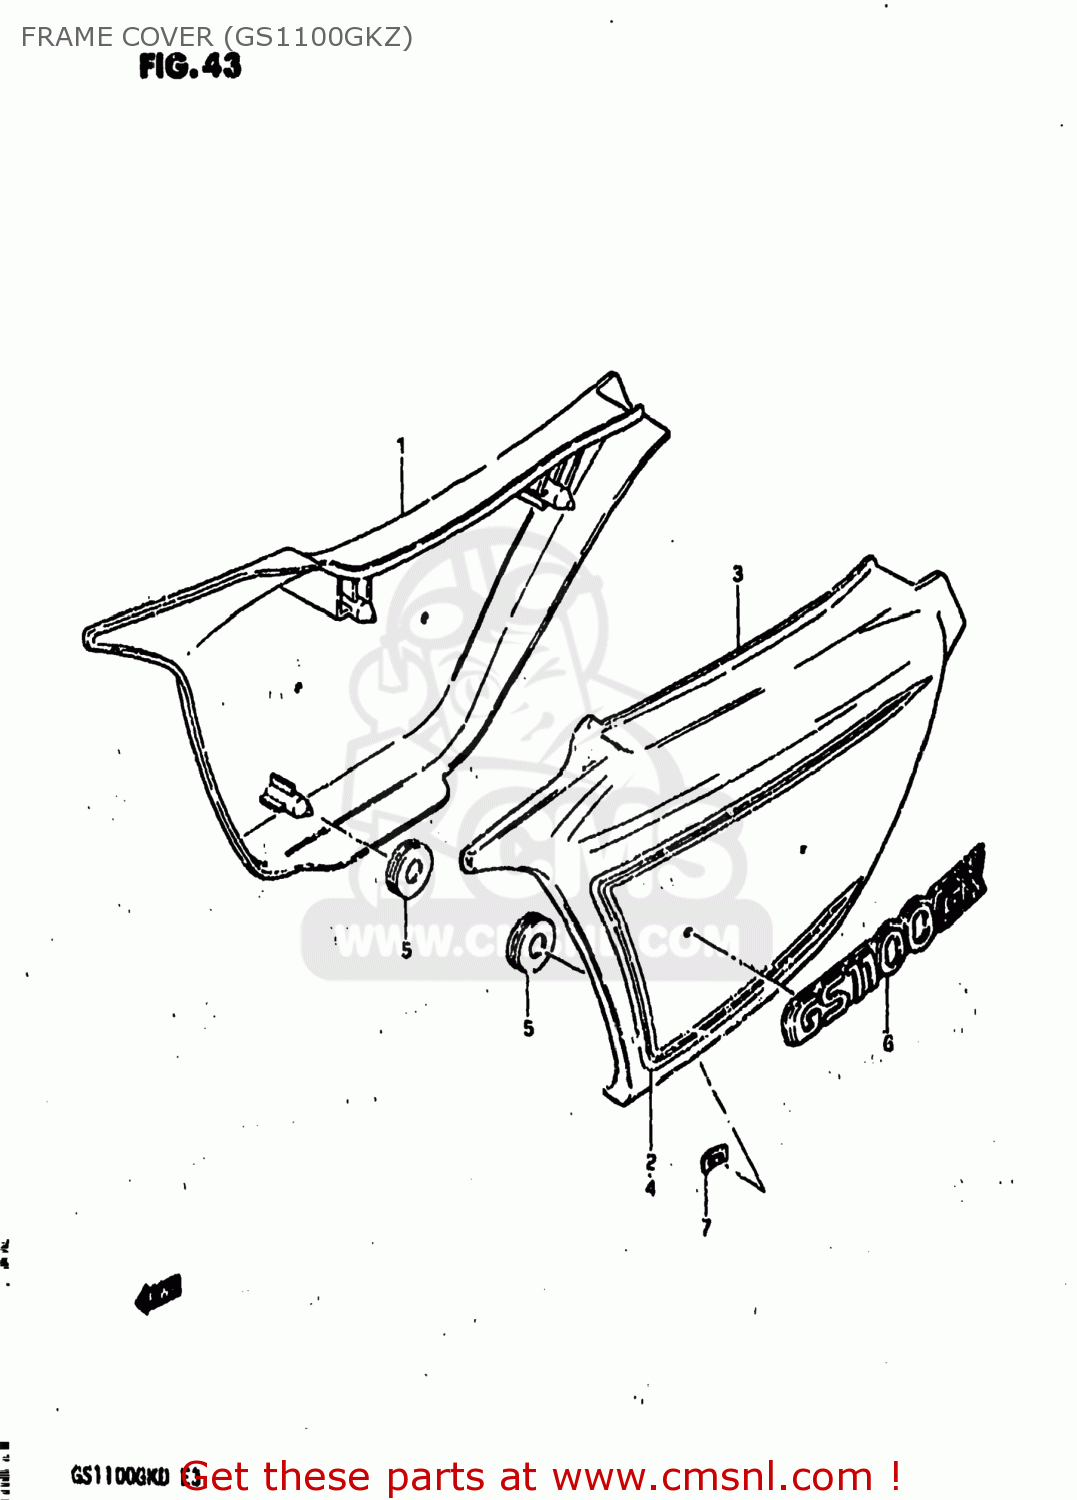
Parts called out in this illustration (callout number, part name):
1	COVER,FRAME,RIGHT
2	TAPE SET,FRAME COVER
3	COVER,FRAME,LEFT
4	TAPE SET,FRAME COVER
5	CUSHION
6	EMBLEM,FRAME COVER
7	NUT
